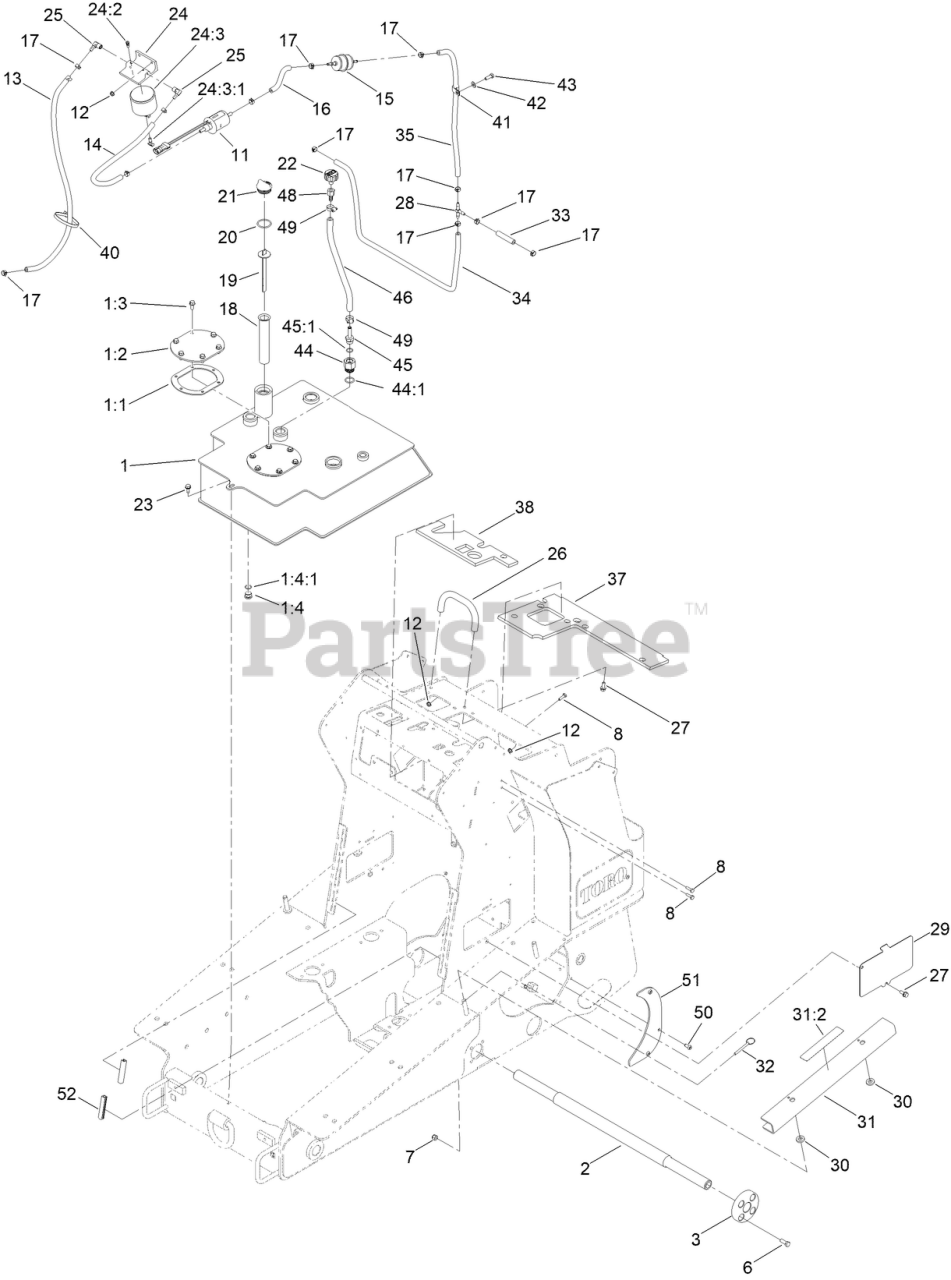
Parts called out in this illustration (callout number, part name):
1	TANK-HYD
1:1	GASKET-COVER, ACCESS
1:2	COVER-TANK
1:3	SCREW-HHF
1:4	PLUG-HEX
1:4:1	O-RING
2	SHAFT-TRACK
3	HUB-SHAFT
6	SCREW-HH
7	NUT-LOCK, NI
8	SCREW-HH
11	PUMP-FUEL, ELECTRIC
12	NUT-HF
13	HOSE-FUEL
14	HOSE-FUEL
15	FILTER-FUEL
16	HOSE-FUEL
17	CLAMP-HOSE
18	FILTER-SCREEN
19	DIPSTICK
20	O-RING
21	PLUG-PLASTIC
22	BREATHER
23	SCREW-THD ROLL, HWH
24	FILTER HEAD ASM
24:2	VENT-AIR
24:3	ELEMENT-SPIN ON
24:3:1	VALVE-DRAIN
25	FITTING-HYD, 90
26	BAR-REFERENCE
27	SCREW-HHF
28	FITTING-TEE, BARBED
29	PLATE-COVER, ACCESS
30	WASHER-NEOPRENE
31	ARM-LOCKING
31:2	DECAL-DANGER
32	PIN-COTTERLESS
33	HOSE-FUEL
34	HOSE-FUEL
35	HOSE-FUEL
37	FOAM-HEAT SHIELD
38	FOAM-HEAT SHIELD
40	TIE-CABLE
41	CLAMP-R
42	WASHER-FLAT
43	SCREW-HH
44	FITTING-STRAIGHT
44:1	O-RING
45	FITTING-STR
45:1	O-RING
48	FITTING-FEMALE, BARBED
49	CLAMP-HOSE
50	PLATE-DIRT
51	SCREW-BHTF
